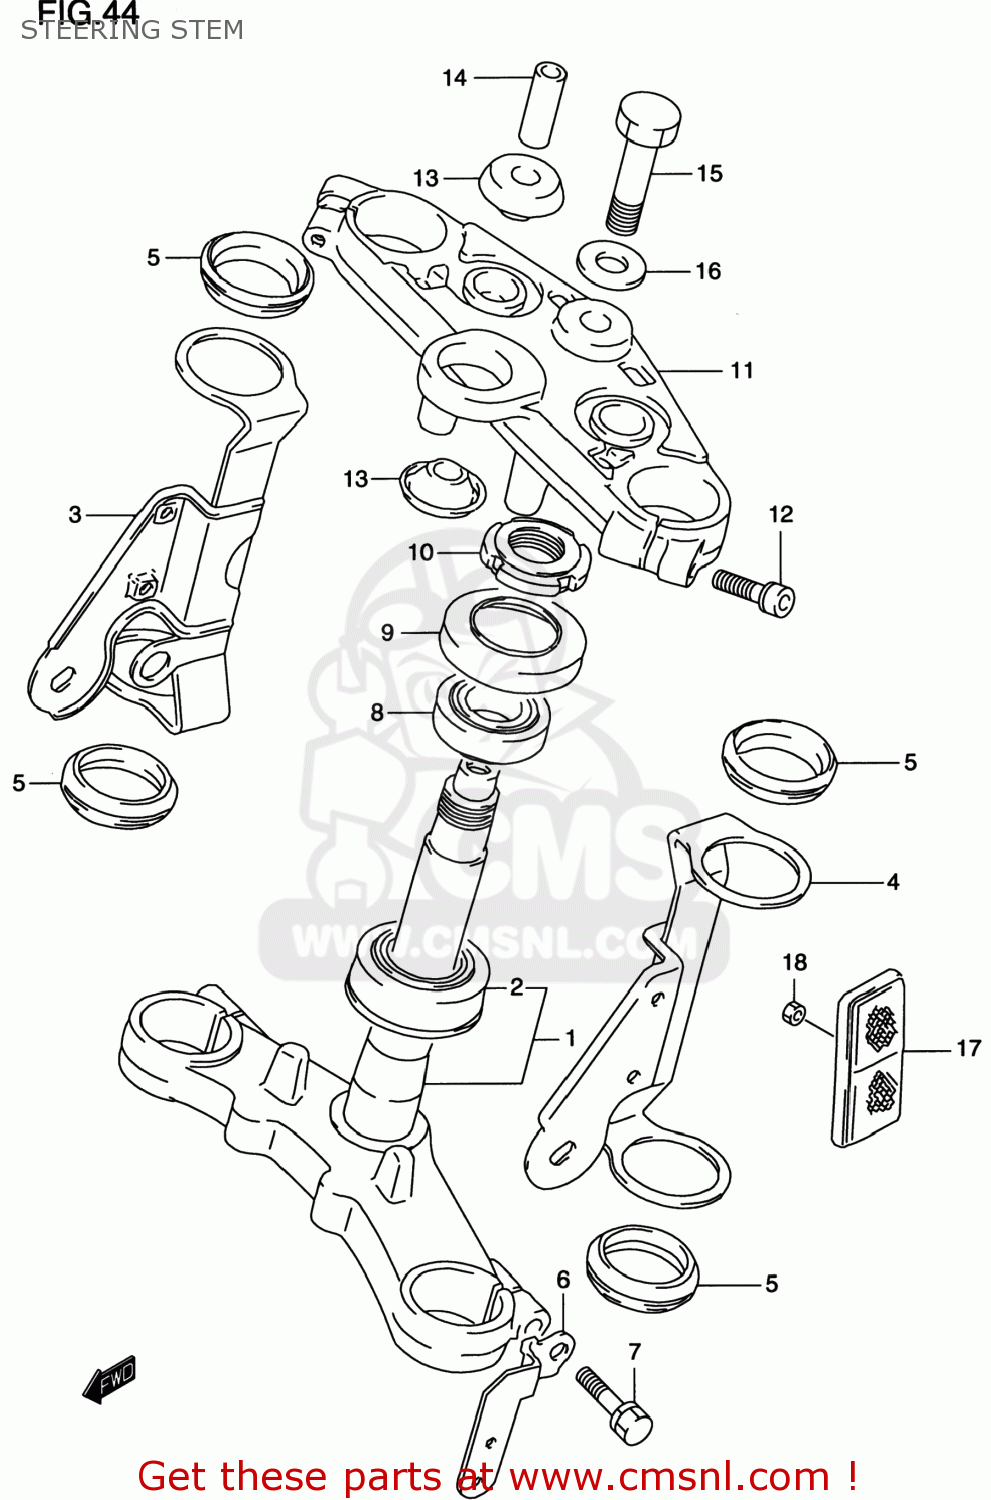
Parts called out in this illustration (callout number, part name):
1	STEM,STEERING
2	BEARING(30X55X17)
3	BRACKET,HEADLAMP,R
4	BRACKET,HEADLAMP,L
5	CUSHION,HEADLAMP BRACKET
6	BRACKET,FR SIDE RR,R
7	BOLT,STEERING STEM
8	BEARING(25X47X15)
9	SEAL,STEERING UPR DUST
10	NUT,STEERING STEM(25X44X10)
11	HEAD,STEERING STEM
12	BOLT
13	CUSHION,UPR BRACKET
14	SPACER,STEERING STEM HEAD
15	BOLT
16	WASHER,STEM HEAD(10.5X30X3.2)
17	REFLEX REFLECTOR,FR SIDE
18	NUT
